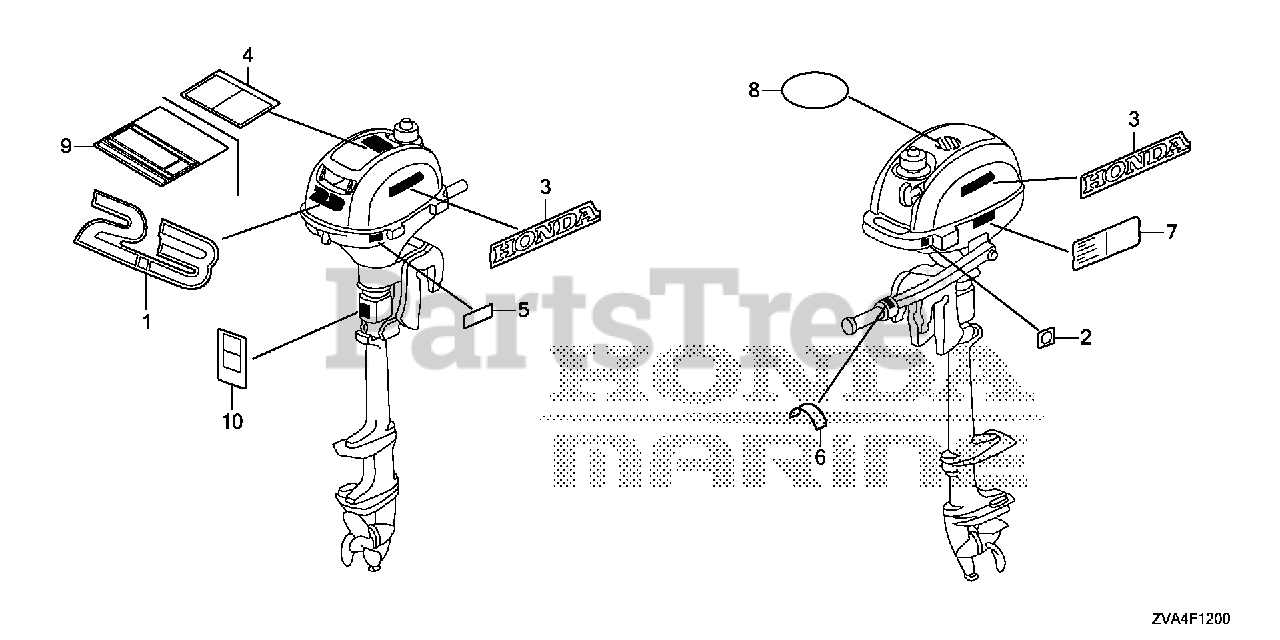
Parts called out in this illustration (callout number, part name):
1	MARK, RR. (2.3)
2	MARK, EMERGENCY SWITCH INDICATION
3	MARK, SIDE STRIPE (HONDA)
5	MARK, FUEL PETCOCK
6	MARK, THROTTLE (ENGLISH)
8	LABEL, RECOIL CAUTION
9	LABEL, OPERATOR CAUTION
10	MARK, EX. CAUTION (ENGLISH)
